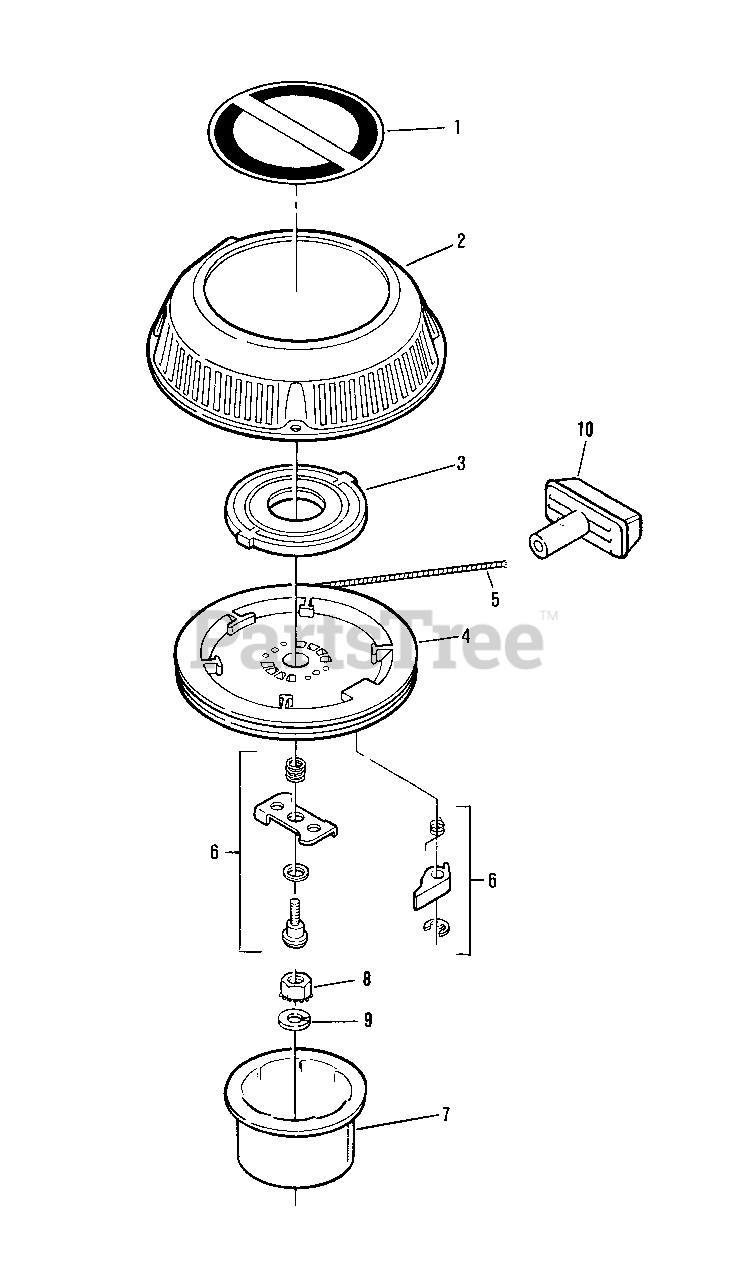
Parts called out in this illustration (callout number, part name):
1	Decal
2	Starter Housing and Shaft Assembly
3	Recoil Spring and Keeper Assembly
4	Pulley
5	Rope
6	Dog Kit Assembly
7	Starter Hub
8	Nut-Flywheel
9	Lockwasher
10	Starter Handle
